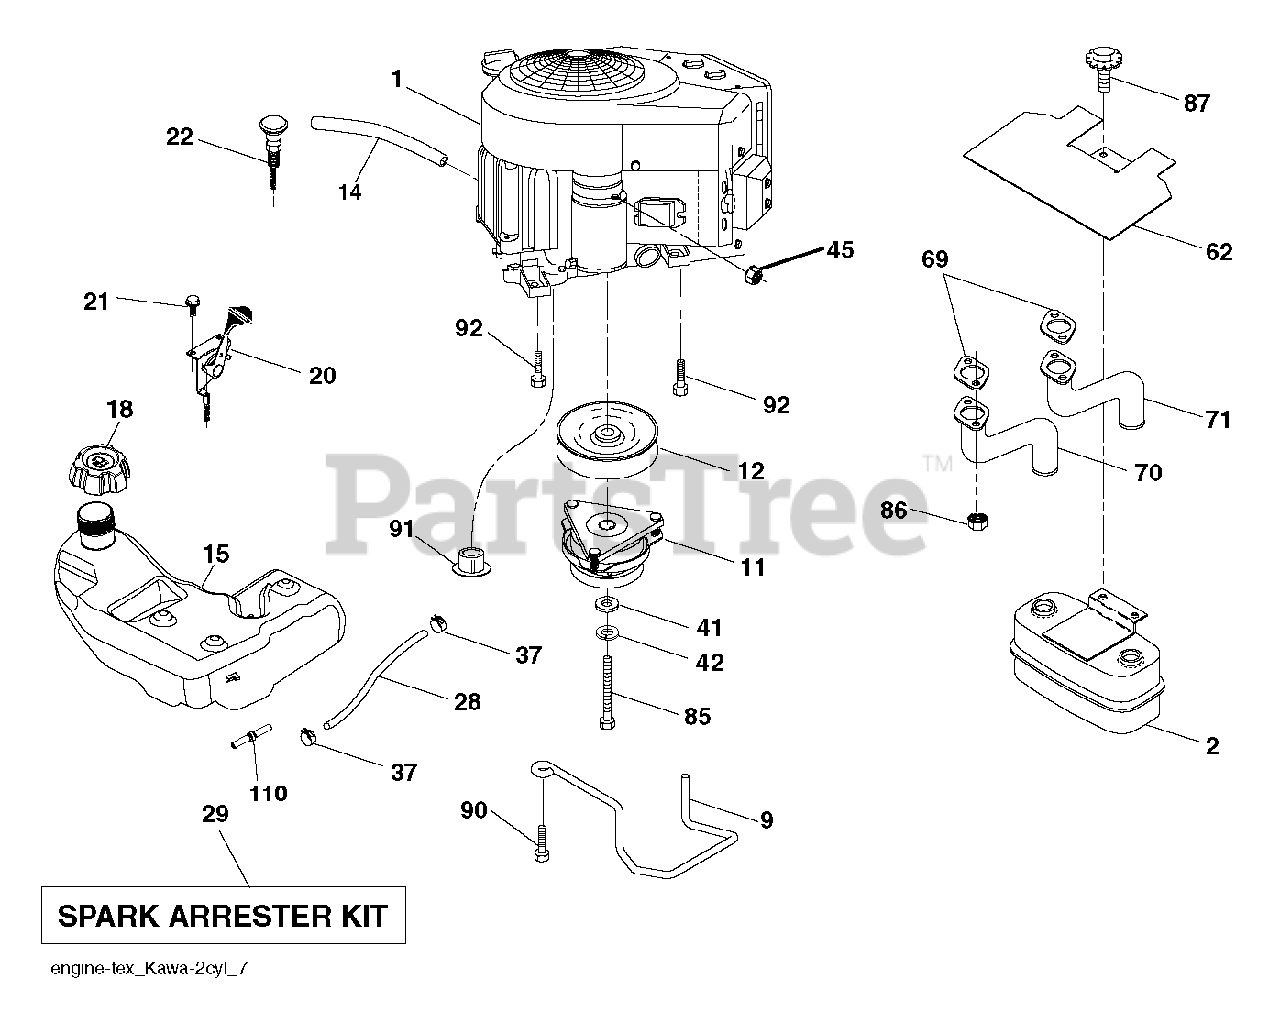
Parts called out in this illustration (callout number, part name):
2	MUFFLER.TWIN.CYL.LOW.TONE
9	KEEPER.BELT.ENGINE.4.2
11	CLUTCH MZ ZTR GT.48/54"1.125"
12	PULLEY ENGINE
14	TUBE, DRAIN OIL ASM.
15	TANK.ASM.4.GAL.EPA.ONE.PORT
18	CAP.ASM.FL.RITCH.3"E10.SYM.498
20	THROTTLE CABLE
21	SCREW.#10 X 0.750.BOS
22	CONTROL.CHOKE.ERGO.PUSH-IN.BLA
28	LINE.FUEL.64"REAR.EMIS
29	KIT.SPARK ARRESTOR 794945 B&S
37	HOSE CLAMP
42	LOCKWASHER
45	NUT
62	SHIELD.HEAT.MUFFLER
70	TUBE.EXHAUST.LH.FR961/FR730
71	TUBE.EXHAUST.RH.FR961/FR730
85	BOLT HEX 7/16-20 X 3.75 GR. 5
86	NUT.HEX.FLANGE.TOPLOCK
87	BOLT.5/16-18UNCX1.W/SEMS.BLK
90	SCREW 3/8-16X1
91	BUSHING.1.375OD
92	SCREW 3/8-16X1
110	VALVE.ASM.ANTI-SLOSH
